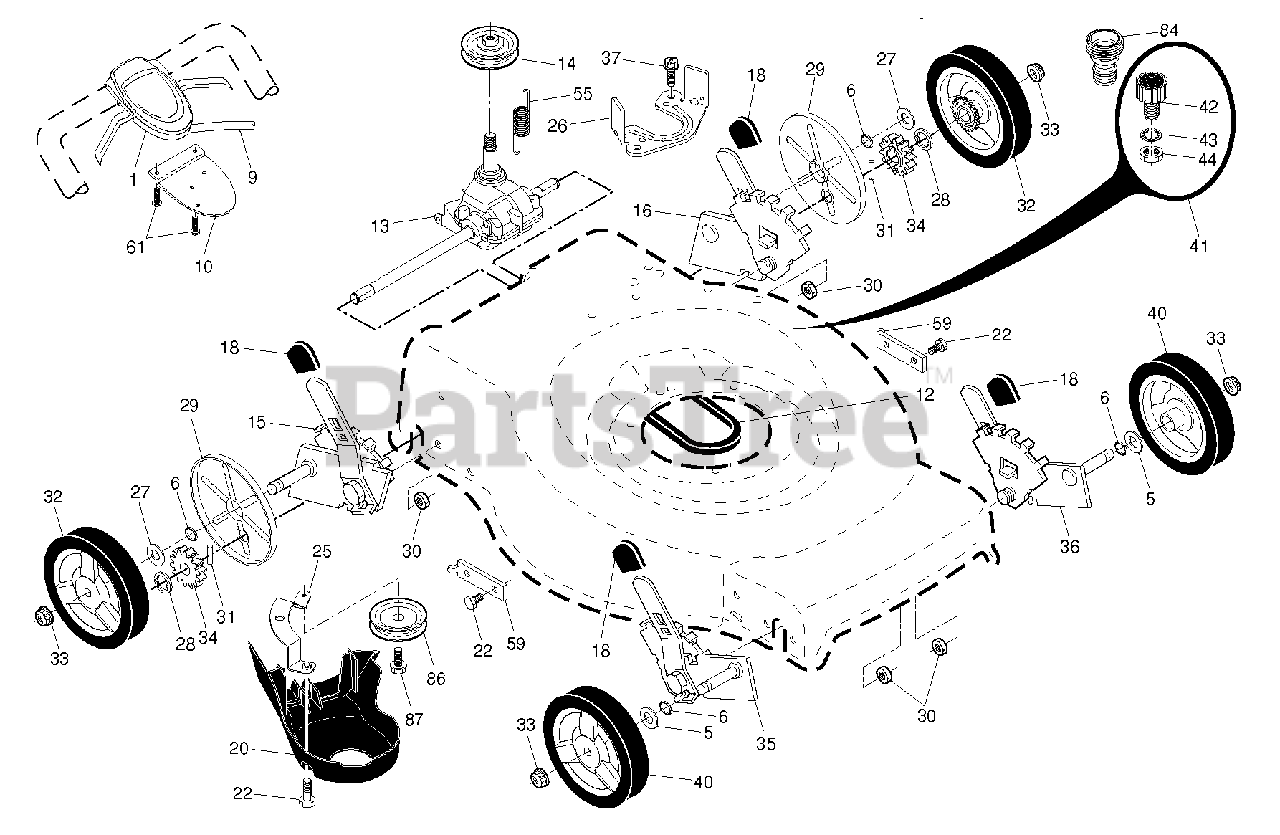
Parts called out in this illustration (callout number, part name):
1	CONTROL.AW2.22+RG.BS.GEN.BK/BK
6	O-RING..070X.487.NEOPRENE
9	CABLE.DRIVE.RWD.WALK.
10	BRACKET.DRIVE.CONTR.GEN2.BLACK
12	BELT.DRIVE.RGD.SS.WALK
13	TRANSMISSION.22+AWD.WALK.MOWER
15	RP_ADJUSTER.ASM.9.22+/RF/LR.21
16	RP ADJ.ASM.9.22+/LF/RR.21/RF
18	SELECTOR KNOB
20	COVER.REAR.DRIVE.22+2013
22	BOLT.5/16HEX.WHS.HD
25	BRACKET.DRIVE.COVER.RGD.
26	BRACKET.TRANS.BELT.KEEPER.BZP
27	WASHER FLUT
28	E-RING 7/16 RE
29	COVER.DUST.WHEEL.INNER.WALK
30	NUT.HEX.FLANGE.1/4
31	PAWL, DRIVE
32	WHEEL.8X1.75.3SPK.RAD3.GREY
33	NUT.HEX.FLANGE.3/8-16.LO(3 2)
34	PINIION.14.TOOTH.RGD
35	ADJUSTER.ASM.9POS.LW.RL/RGD.FR
36	ADJUSTER.ASM.9POS.LW.RR/RGD.
40	WHEEL & TIRES ASSY, FRONT
41	KIT.WASH-OUT.PORT.ZINC.WALK
42	WASHOUT.PORT.ZINC.RGD.22+
43	WASHER.LOCK.INTERNAL.TOOTH
44	LOCKNUT.HEX.WITH.O-RING
55	SPRING.RETURN.AUTO.
59	BRACKET.SUPPORT.22+RWGD.BZP
61	SCREW, PHILLIPS HEAD 10 X 5/8
84	COUPLING.QUICK CONNECT
86	RP PULLEY.AWD.IDLER
